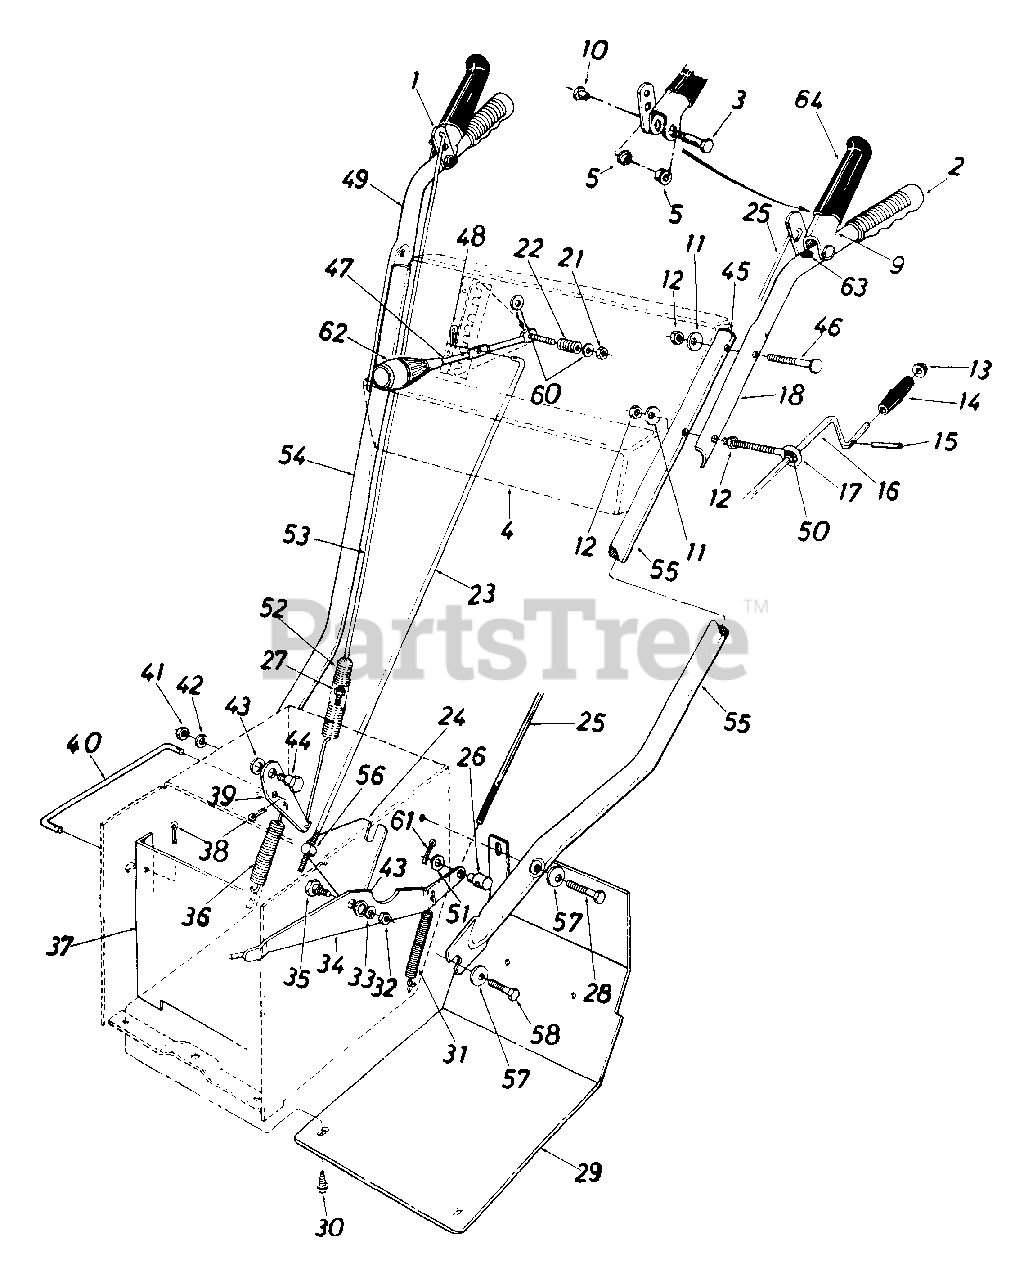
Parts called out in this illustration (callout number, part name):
1	Clutch Grip Ass'y. - R.H.
2	Grip - Red
3	Shoulder Bolt .374 Dia. x 1.375" Lg.
4	Handle Panel Ass y.
5	Hex Flange Plastic Bearing .380" I.D.
9	Clutch Grip Ass'y. - L.H.
10	Shoulder Nut 1/4-20 Thd.
11	Bell-Wash. .34" I.D. x .88" O.D.
12	Hex Nut 5/16-18 Thd.
13	Push Nut 3/8" Rod
14	Knob 3/8" Rod
15	Roll Pin .12 Dia. x .63" Lg.
16	Chute Crank Ass'y. 39" Lg.
17	Eye Bolt 5/16-18 x 5.0" Lg.
18	Upper Handle - L.H.
21	Hex Ins. Jam L-Nut 5/16-18 Thd
22	Compression Spring .50" O.D. x .88" Lg.
23	Shifting Rod 5/16" x 32.50" Lg.
24	Shifting Linkage Bracket
25	Lockout Rod .214" Dia. x 36.0" Lg.
26	Adjustment Ferrule 1/4-20
27	Hex Ins. L-Nut 1/4-20 Thd.
28	Hex Bolt 3/8-16 x 2.00" Lg.
29	Frame Cover
30	Hex Wash. Self-Tap Scr. 1/4-20 x .50" Lg.
31	Extension Spring .38" O.D. x 3.25" Lg.
32	Hex Jam Nut 3/8-16 Thd.
33	L-Wash. 3/8" I.D.
34	Auger Clutch Bracket Ass'y.
35	Shld. Bolt .625" Dia. x .170
36	Extension Spring .75" O.D. x 4.31" Lg.
37	Drive Pulley Support Brkt. Ass'y.
38	Cotter Pin 3/32" Dia. x .75" Lg.
39	Drive Clutch Bracket
40	Drive Clutch Rod
41	Hex Jam Nut 3/8-16 Thd.
42	L-Wash. 3/8" I.D.
43	Bell-Wash. .40" I.D. x 1.13" O.D.
44	Shld. Bolt .625" Dia. x .170
45	Plastic Plug
46	Carriage Bolt 5/16-18 x 2.0" Lg.
47	Shift Handle
48	Int. Cotter Pin 5/16" Dia.
51	Fl-Wash. .344" I.D. x .62" O.D.
52	Extension Spring .75" O.D. x 5.00" Lg.
53	Lockout Rod .214" Dia. x 32" Lg.
54	Lower Handle - R.H.
55	Lower Handle - L.H.
56	Adjustment Ferrule
57	Bell-Wash. .40" I.D. x .88" O.D.
58	Hex Wash. Self-Tap Scr. 3/8-16 x .75" Lg.
60	Fl-Wash. .344" I.D. x .62" O.D.
61	Cotter Pin 3/32" Dia.
63	Push Cap
64	Black Vinyl Grip
